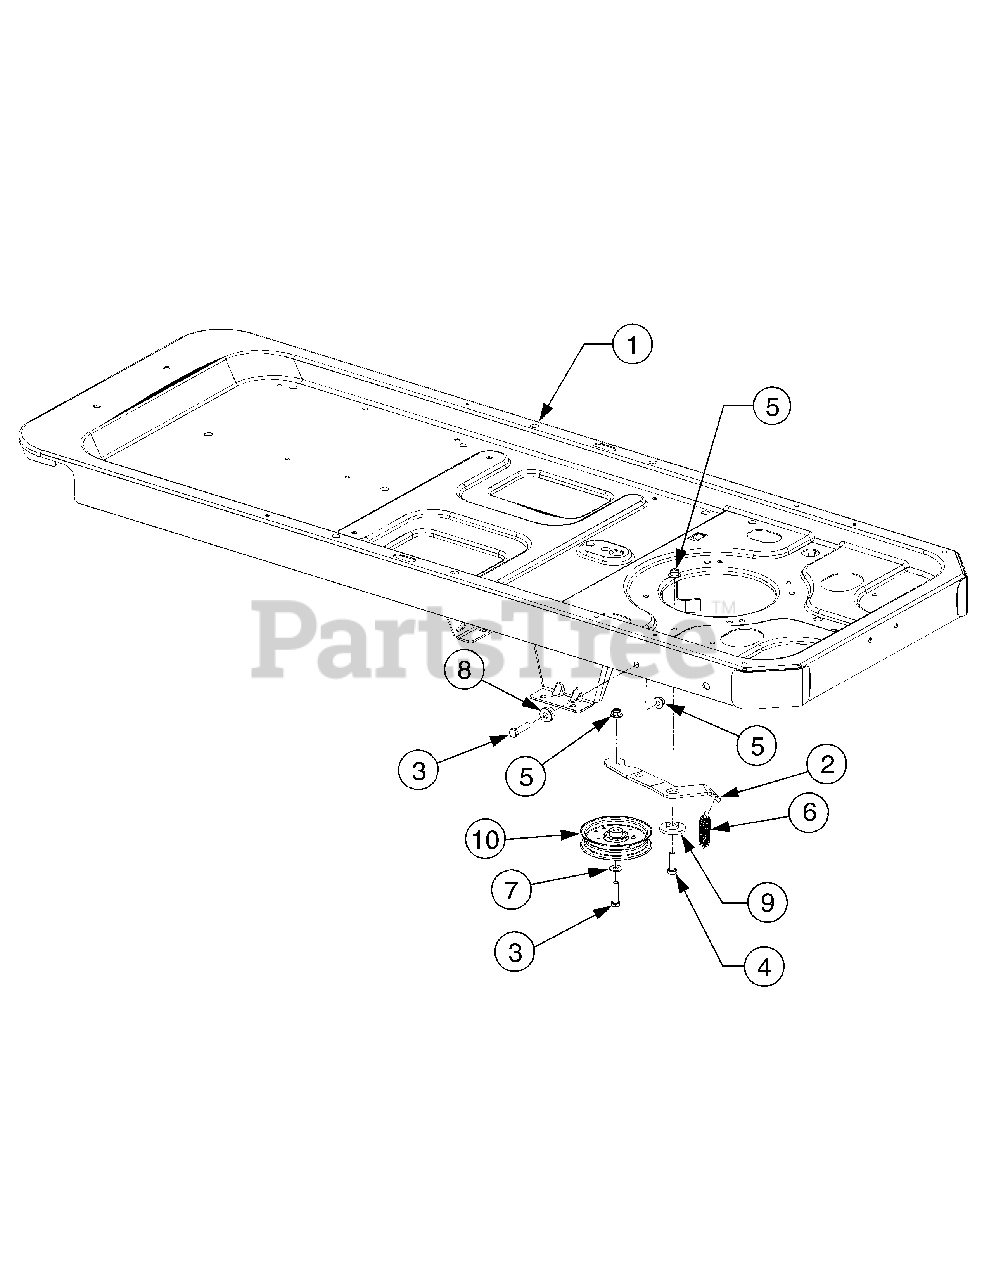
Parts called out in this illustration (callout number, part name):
3	Screw, Hex Cap, 3/8-16 x 1.5 GR5
4	Screw, Hex Cap, 3/8-16 x 1.25 GR5
5	Nut, Hx Insert Flnge Lck, 3/-16 GrF
6	Spring, Extension, .75 x 5.06
7	Washer, Flat, .408 x .875 x .059
8	Spacer, Shoulder, .39 x 1.0 x .7
9	Spacer, Shoulder, .884 x .19
10	Pulley, Idler, 4.25 Dia.
